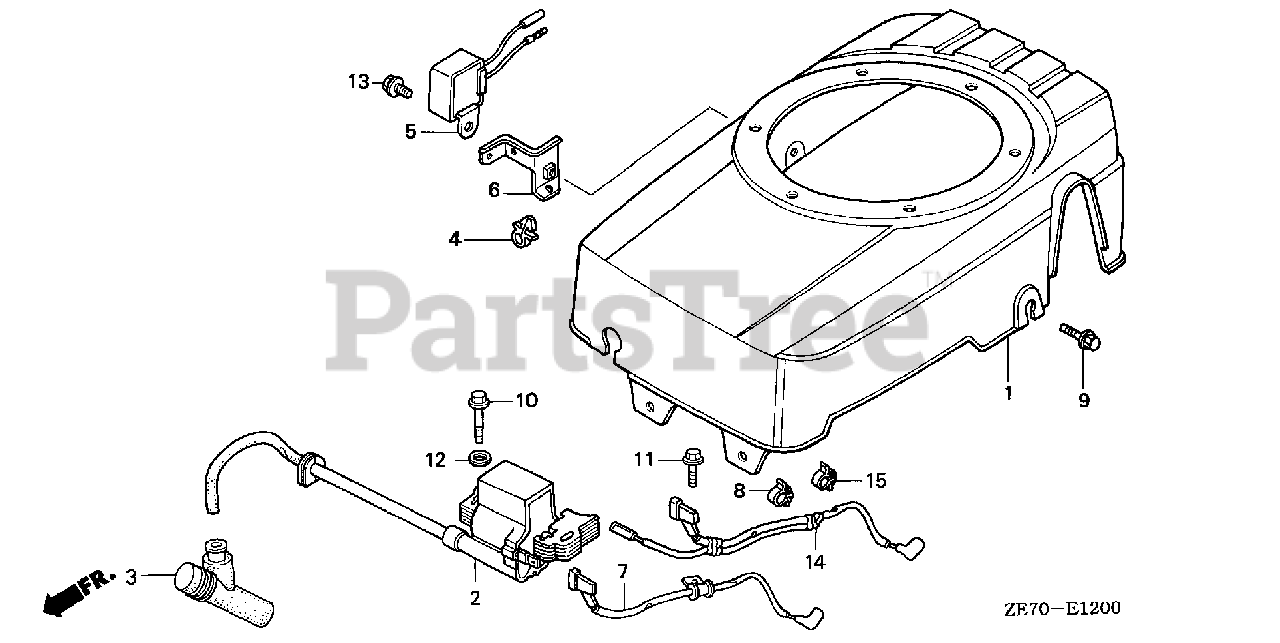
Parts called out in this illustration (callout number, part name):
1	COVER, FAN *R8* (BRIGHT RED)
2	COIL ASSY., IGNITION
3	CAP ASSY., NOISE SUPPRESSOR
8	HOLDER, STOP SWITCH WIRE
9	BOLT, FLANGE (6X14) (CT200)
10	BOLT, FLANGE (6X25) (CT200)
11	BOLT, FLANGE (5X10)
14	WIRE, STOP SWITCH (BRAKE)
15	CLIP, WIRE HARNESS (6MM) (WHITE)
